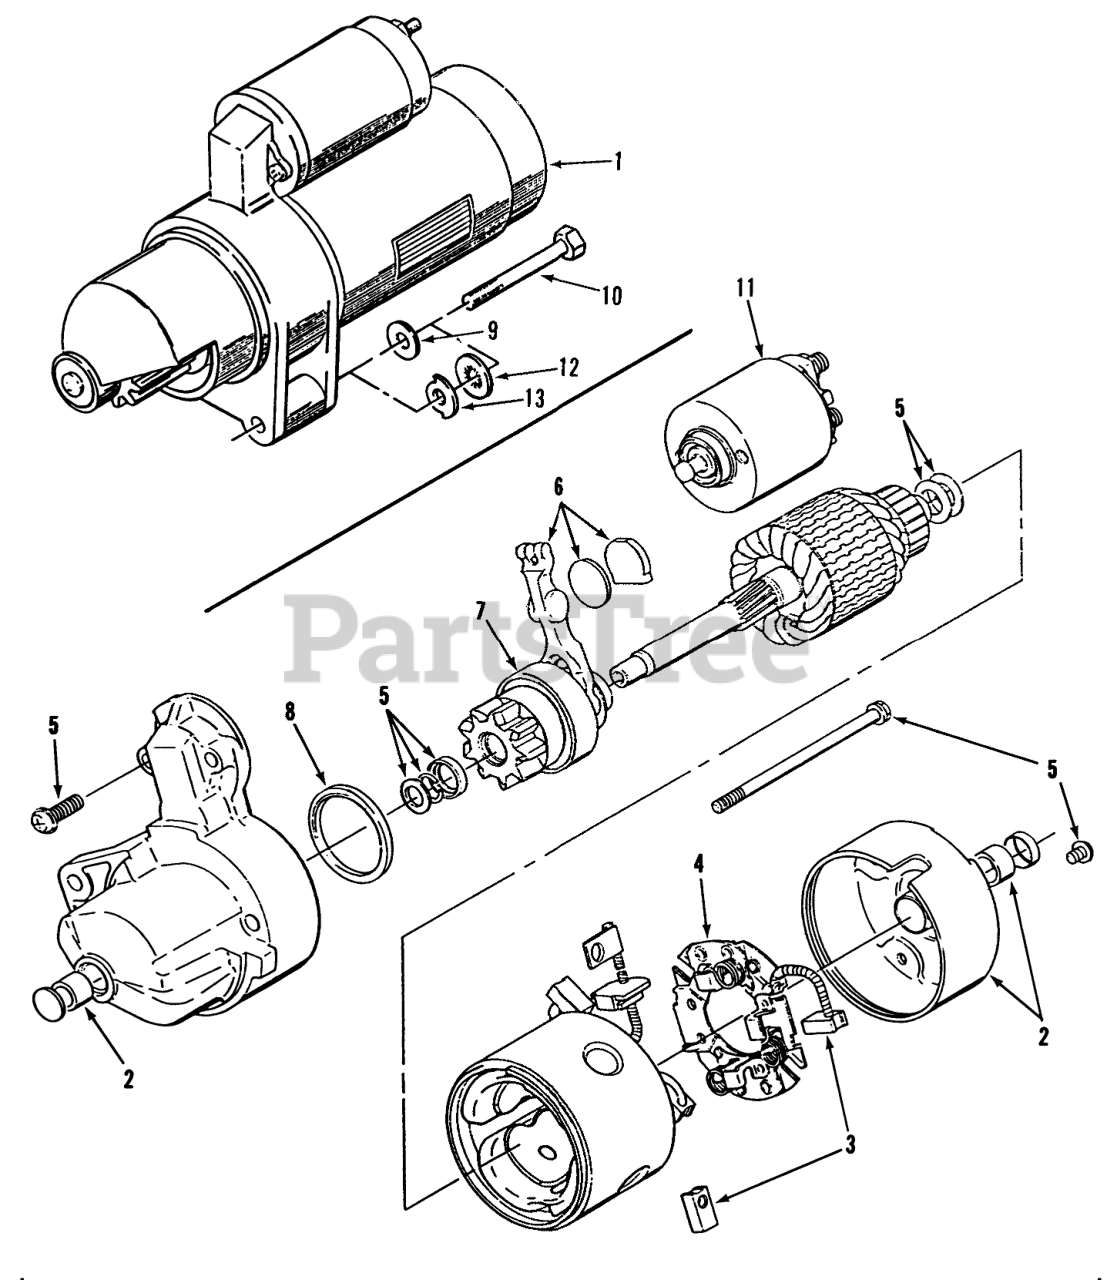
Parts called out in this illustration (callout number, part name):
1	Starter, Complete-See Components Below
2	Bushing Kit (Includes Front Bushing and Rear Cap w/Bushing)
3	Starter Brush Kit (Includes Positive Brush (2) and Negative Brush w/Pigtail)
4	Starter Brush Holder (Includes Brush Holder w/Negative Brush)
5	Starter Holder Kit (Includes Solenoid Screws (2), Brush Holder Screws (2), Thru Bolts (2), Armature Shims (2), Pinion Stop Collar, and Pinion Retaining Ring)
6	Starter Shift Lever Kit (Includes Shift Lever, Wear Plate and Rubber Plug)
7	Starter Clutch (Includes Pinion Gear w/Clutch)
8	Dust Seal
9	Washer
10	Bolt
11	Starter Solenoid Kit (Includes Solenoid, Spring and Plunger)
12	WASHER
13	WASHER
